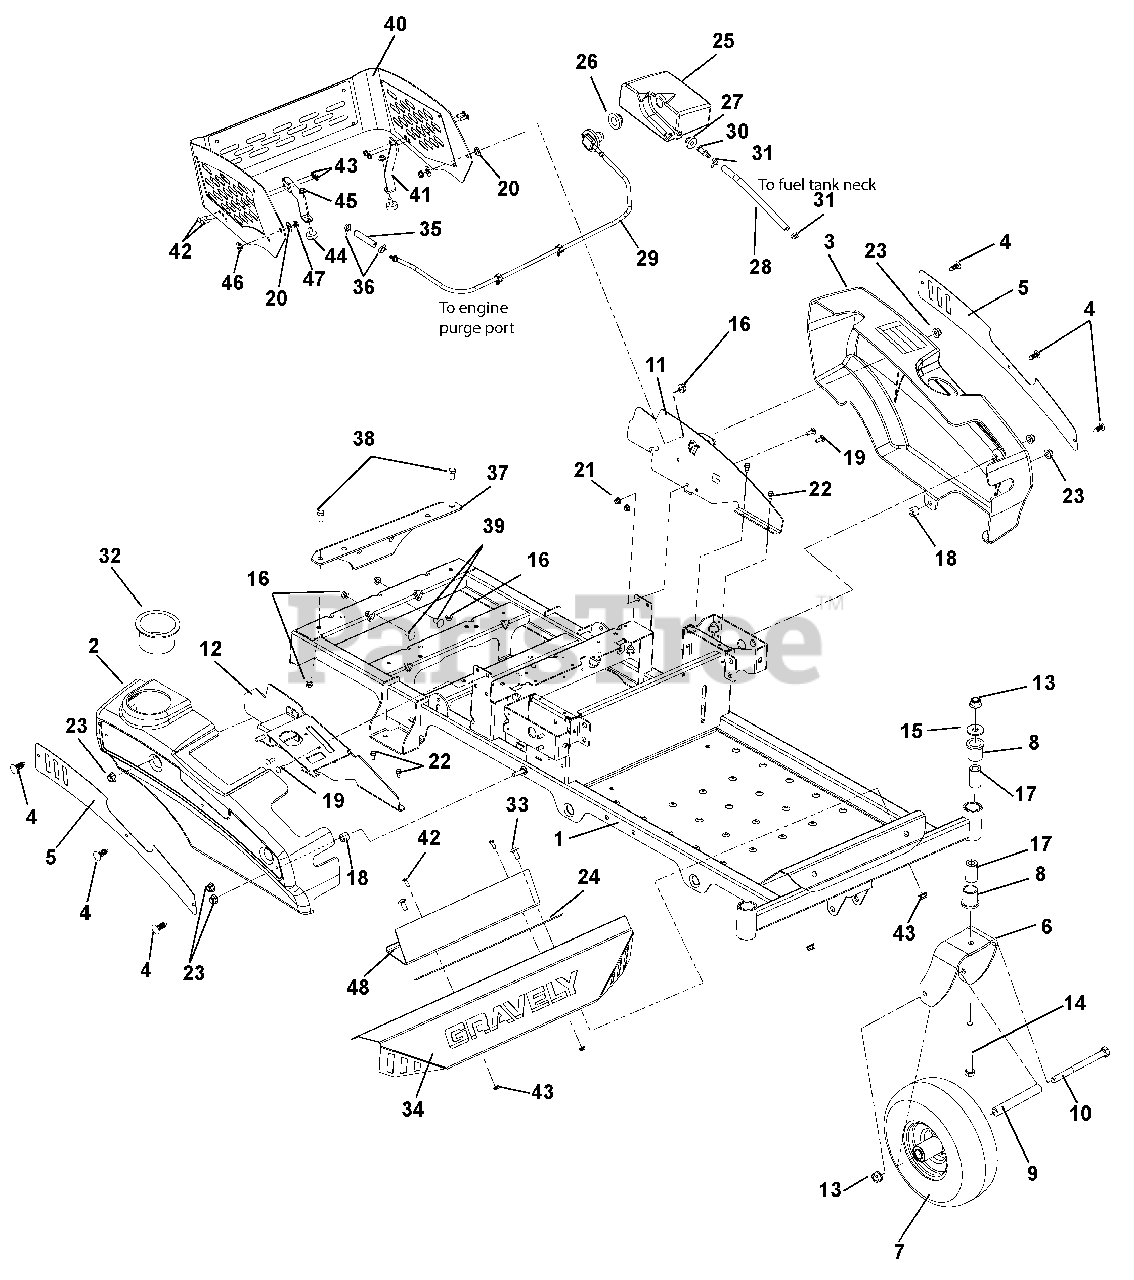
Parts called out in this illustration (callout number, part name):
1	Weldment, Frame
2	Fender, Right Hand
3	Fender, Left Hand
4	Rivet, Nylon
5	Plate, Fender
6	Fork, Caster
7	Wheel/Tire Assembly, 11 x 4-5
8	Bushing, Flange 1.00 x 1.25 x 1.50 x 1.50
9	Spacer, Wheel
10	Bolt, Hex .50-13 x 6.50
11	Weldment, Left Hand Fender Mount
12	Weldment, Right Hand Fender Mount
13	Nut, Locking Top Flange .50-13
14	Bolt, Hex .50-13 x 5.00
15	Washer, Flat Steel .511 x 1.441 x .125
16	Nut, Locking Top Flange .38-16
17	Spacer, Caster
18	Bushing, Sleeve .391 x .688 x .52
19	Bolt, Round Head Square Neck .25-20 x .75
20	Washer, Flat Nylon .52 x 1.00 x .08
21	Nut, Locking Top Flange .25-20
22	Screw, Tapping .25-20 x .50 Hex Washer Head Thread
23	Nut, Locking Nylon Flange .31-18
24	Grip, Adhesive (1" x 16" BLK)
25	Tank, ZT/Waw Fuel Expansion
26	Grommet, Remote Vent Nitrile
27	Bushing, Flange .375 x 1.062 x .625
28	Hose, .25 Low-Perm Bulk Gas (7 inches)
29	Assembly, Fuel Vent – Kohler, Briggs and Stratton (915146)
30	Fitting, Straight Fuel
31	Clamp, Hose Wire .490/.510 x .116
32	Cupholder, Snap-In, 3.75 OD
33	Bolt, Round Head Square Neck .31-18 x .75
34	Foot Rest
35	Hose, .188 Low-PERM Bulk Gas (as required)
36	Clamp-Hose, Spring .188
37	Plate, BBZ Hitch Kit Plate (915148, 150)
38	Bolt, Hex .38-16 x .75 (915148, 150)
39	Bolt, Round Head Square Neck .31-16 x .75 (915148, 150)
40	Assembly, Engine Wrap
41	Bracket, Engine Wrap Foot
42	Bolt, Round Head Square Neck .25-20 x .50
43	Nut, Center Lock Flange .25-20
44	Bumper, Rubber
45	Nut, Serrated Flange .31-18
46	Bushing, Flange .325 x .499 x .3 x .875
47	Nut, Center Lock Flange .31-18
48	Plate, Back Foot Rest
